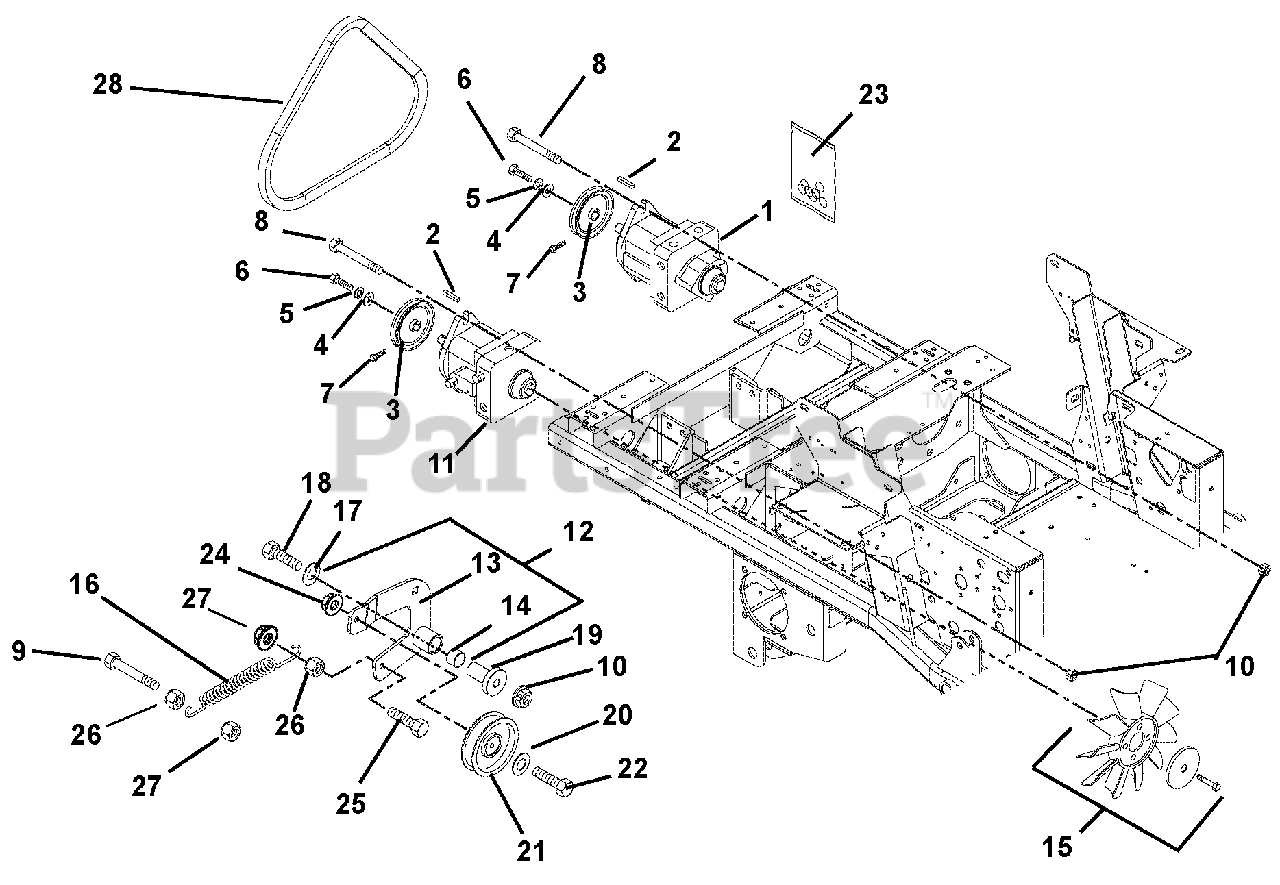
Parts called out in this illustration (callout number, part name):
1	PUMP - HYDRAULIC RTN W/AUX
2	KEY, SQ 5 X 5 X 30MM PLAIN
3	SHEAVE - POLY-V .671 X 4.125
4	WSHR-FL-STL .281X1.000X.063
5	@WSHR-LK .25X.062 REG YWZC
6	BLT-HEX M6X1.0X12 YZ EP30
7	SCR-SKH .25-20X.50 YZ EP80
8	@BLT-HEX .50-13X1.50 GR5 YWZC
9	@BLT-HEX .31-18X2.50 GR5 YWZC
10	@NUT-LK-TOP-FLG .50-13 YWZC
11	PUMP-HYD RTN THRU SHAFT F/FAN
12	ASSEMBLY, IDLER ARM
13	WMT, IDLER ARM
14	BSHG, 1.00 X 1.125 X 1.937
15	FAN KIT, HYDROGEAR 70618
16	SG-TENS .135X.69X5.75 WLD 150
17	@WSHR-FL-STL.563X1.38X.109YWZC
18	@BLT-HEX .50-13X3.50 GR5 YWZC
19	BEARING, PEDESTAL
20	@WSHR-FL-STL.406X.812X.065 YWZ
21	ASM, IDLER 4"
22	@BLT-HEX .38-16X2.00 GR5 YWZC
23	KIT, PUMP SEAL (BDP-21L)
24	@NUT-LK-TOP-FLG .38-16 YWZC
25	@BLT-HEX .31-18X1.25 GR5 YWZC
26	@NUT-HEX .31-18 YWZC
27	@NUT-LK-TOP-FLG .31-18 YWZC
28	POLY V-BELT, K-5 RIBS
